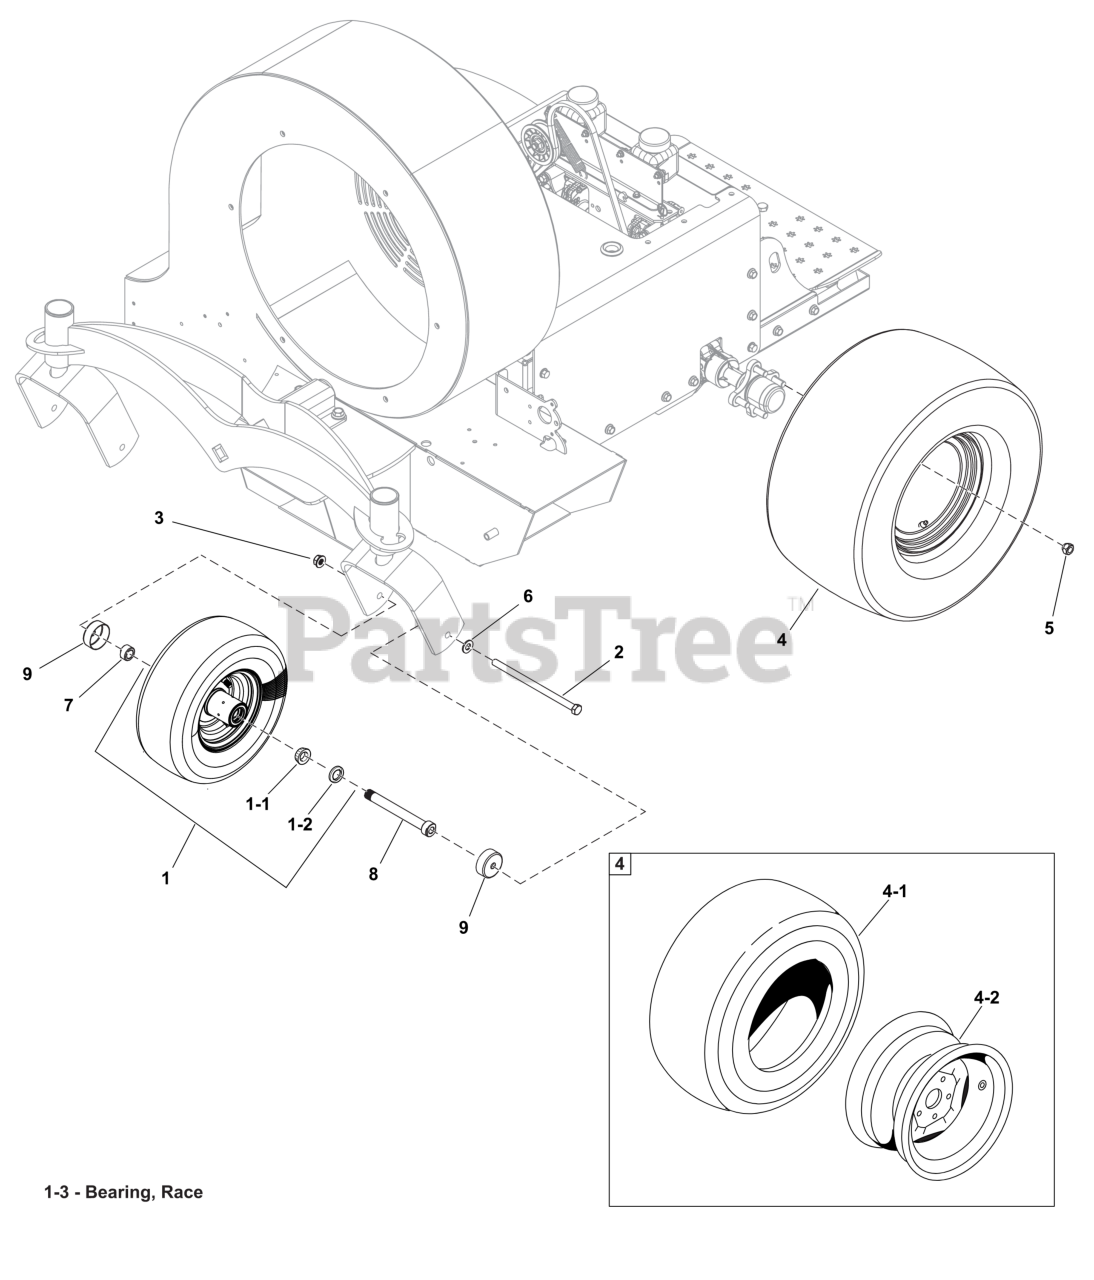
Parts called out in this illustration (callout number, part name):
1	TIRE ASSEMBLY
1-1	BEARING, Tapered Roller
1-2	SEAL, GREASE
1-3	BEARING, RACE
2	BOLT, 1/2-13 X 9 GD5
4	TIRE ASSEMBLY
4-1	TIRE, 22-11.00 X 10, 4-PLY (TIRE ONLY)
4-2	WHEEL RIM
5	NUT, 1/2-20, FOR WHEEL BOLT SILVER
6	WASHER, 1/2" SAE
7	NUT, BEARING
8	BEARING ADJUSTER
9	DEBRIS, COVER, WHEEL
